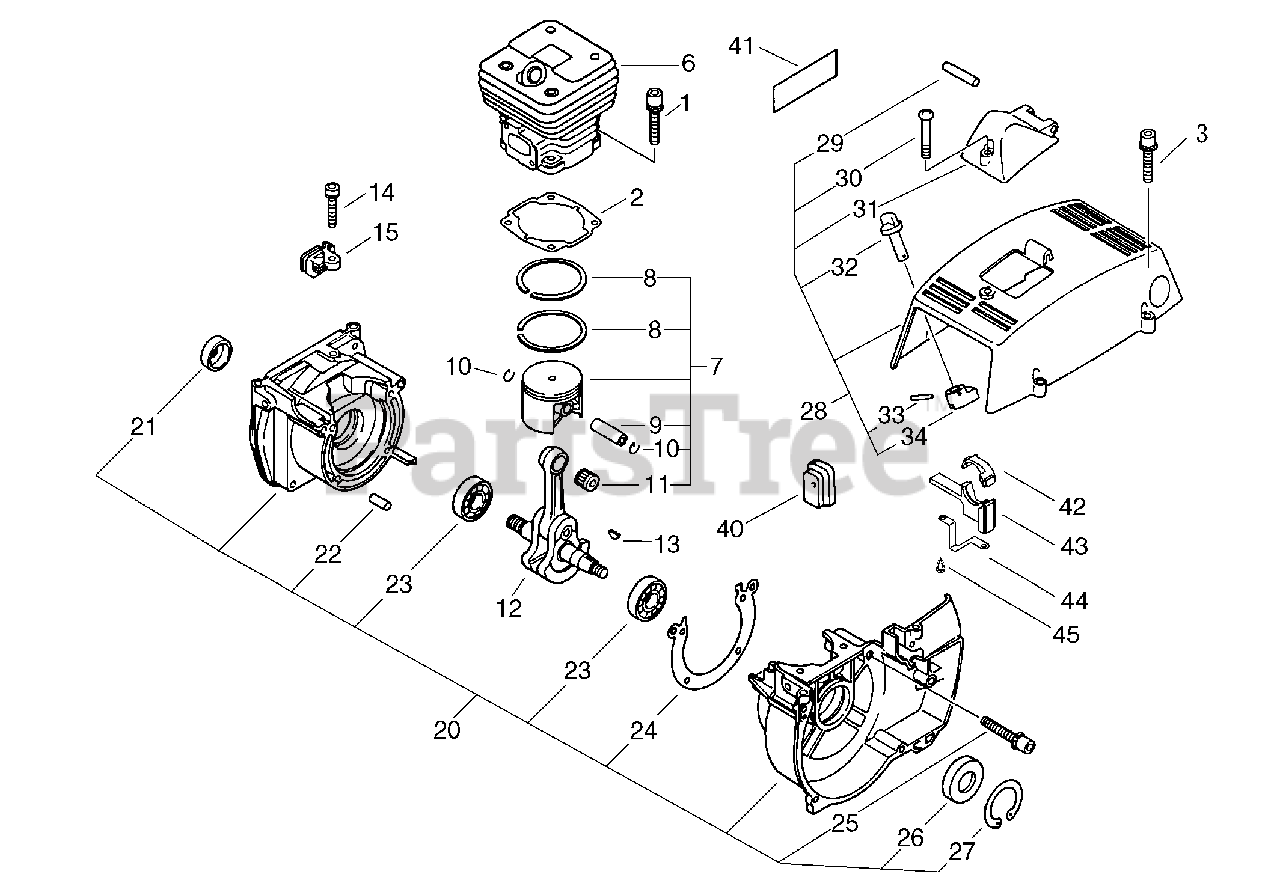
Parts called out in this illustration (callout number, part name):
1	SCREW - 5X22
2	GASKET, CYLINDER
3	SCREW - 5X22
6	CYLINDER
7	PISTON KIT
8	RING, PISTON
9	PIN, PISTON
10	RING, RETAINING
11	BEARING, NEEDLE
12	CRANKSHAFT ASSY
13	KEY - 3X14
14	SCREW - 5X16
15	BRACKET, THROTTLE CABLE
20	CRANKCASE KIT
21	SEAL, OIL
22	PIN - LOCATING
23	BEARING, BALL - 6202
24	GASKET, CRANKCASE
25	SCREW - 5X35
26	SEAL, OIL
27	RING, RETAINING - 35
28	COVER, CYLINDER
30	SCREW - 5
31	COVER, PLUG CAP
32	ROD, CHOKE
33	PIN - SPRING -- 2X10
34	END, LEVER
41	LABEL - ECHO
44	BRACKET
45	SCREW - 4X16
